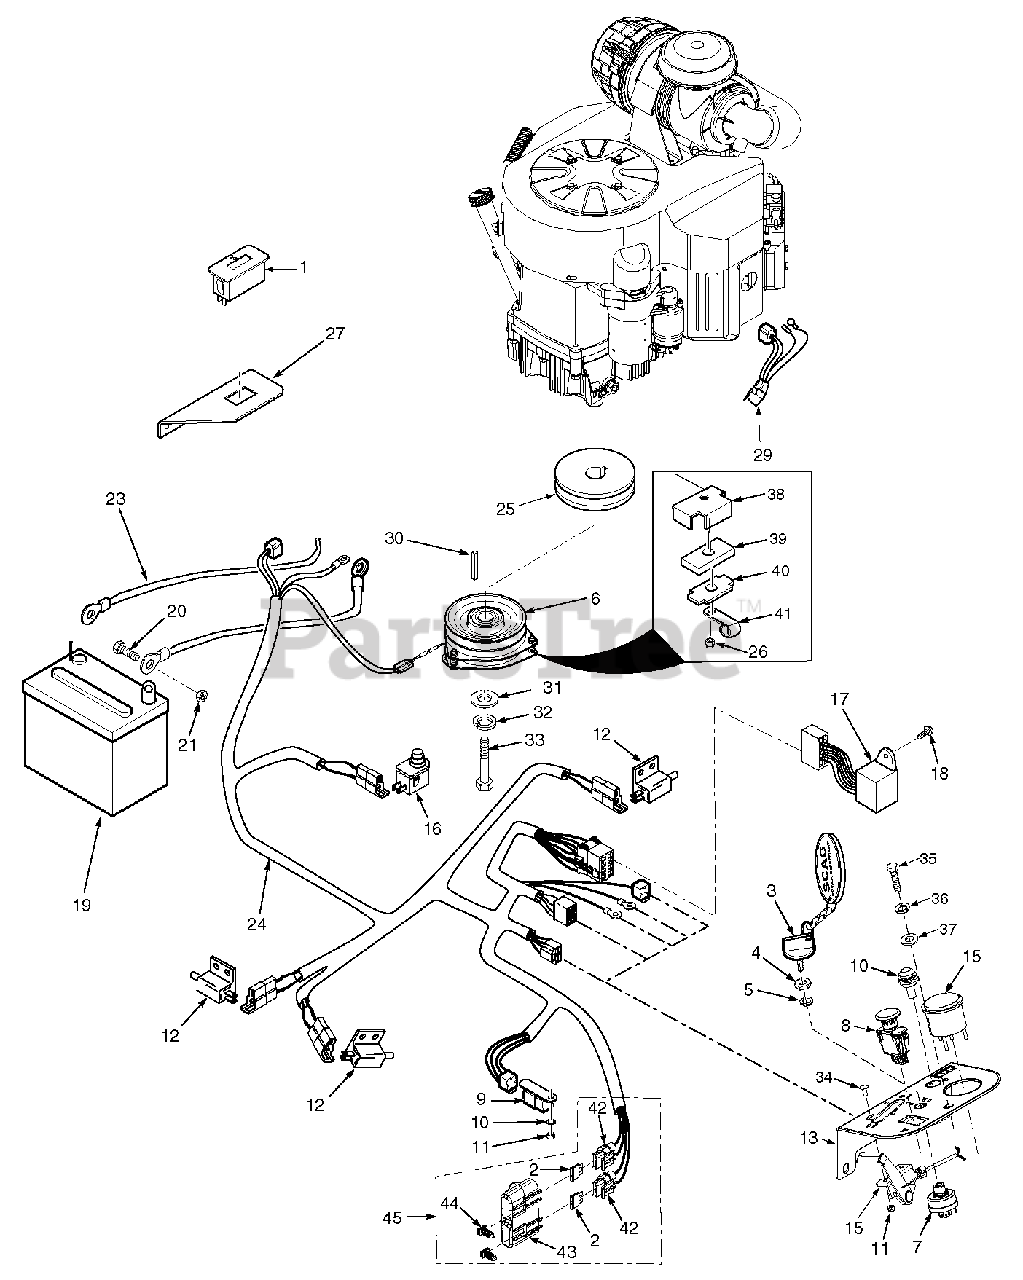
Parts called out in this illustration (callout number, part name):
1	Hourmeter
2	Fuse, 20 amp
3	Key, Ignition
3	Key Assembly w/Fob
4	Nut, Hex 5/8-32
5	Lockwasher, 5/8" Internal
6	Electric PTO Clutch GT3.5
7	Switch, Ignition
8	Switch, PTO
9	Relay
10	Indicator Light Assembly
11	Nut, Elastic Stop #10-24
12	Switch, N/O
13	Panel, Instrument w/Decal (Kohler EFI)
14	Throttle Control
15	Voltmeter
16	Switch, Seat
17	Module, Interlock
18	Screw, #10-32 x .5" Phillips Head
19	Battery, 350CCA (Not Available Through Scag)
20	Bolt, Hex Head 1/4-20 x .5"
21	Nut, Hex 1/4-20
22	Cable, Battery Black (negative)
23	Cable, Battery Red (positive)
24	Wiring Harness, Main (Kohler EFI)
25	Pulley, 5.45 OD x 1.125" Bore
26	Nut, Elastic Stop 5/16-18 Key
27	Mounting Bracket, Hour Meter
28	Screw, #10-32 x 1.5" Phillips Head
29	Adapter, Wiring Harness (Kohler EFI only)
30	Key, 1/4 x 1/4 x 3-1/4"
31	Flatwasher, 7/16-.469 x 1-3/4" x 1/4"
32	Lockwasher, 7/16"
33	Bolt, Hex Head 7/16-20 x 2-1/2" UNF
34	Bolt, Carriage #10-24 x 3/4"
35	Bolt, Hex Head 5/16-18 x 3/4"
36	Lockwasher, 5/16"
37	Flatwasher, 5/16-.375 x .875 x .083
38	Backing Plate
39	Rubber Pad, Clutch Stop
40	Plate, Backing
42	Fuse Holder
43	Cover, Sealed Double
44	Clip, Wire
45	Double Fuse Assembly, Sealed
